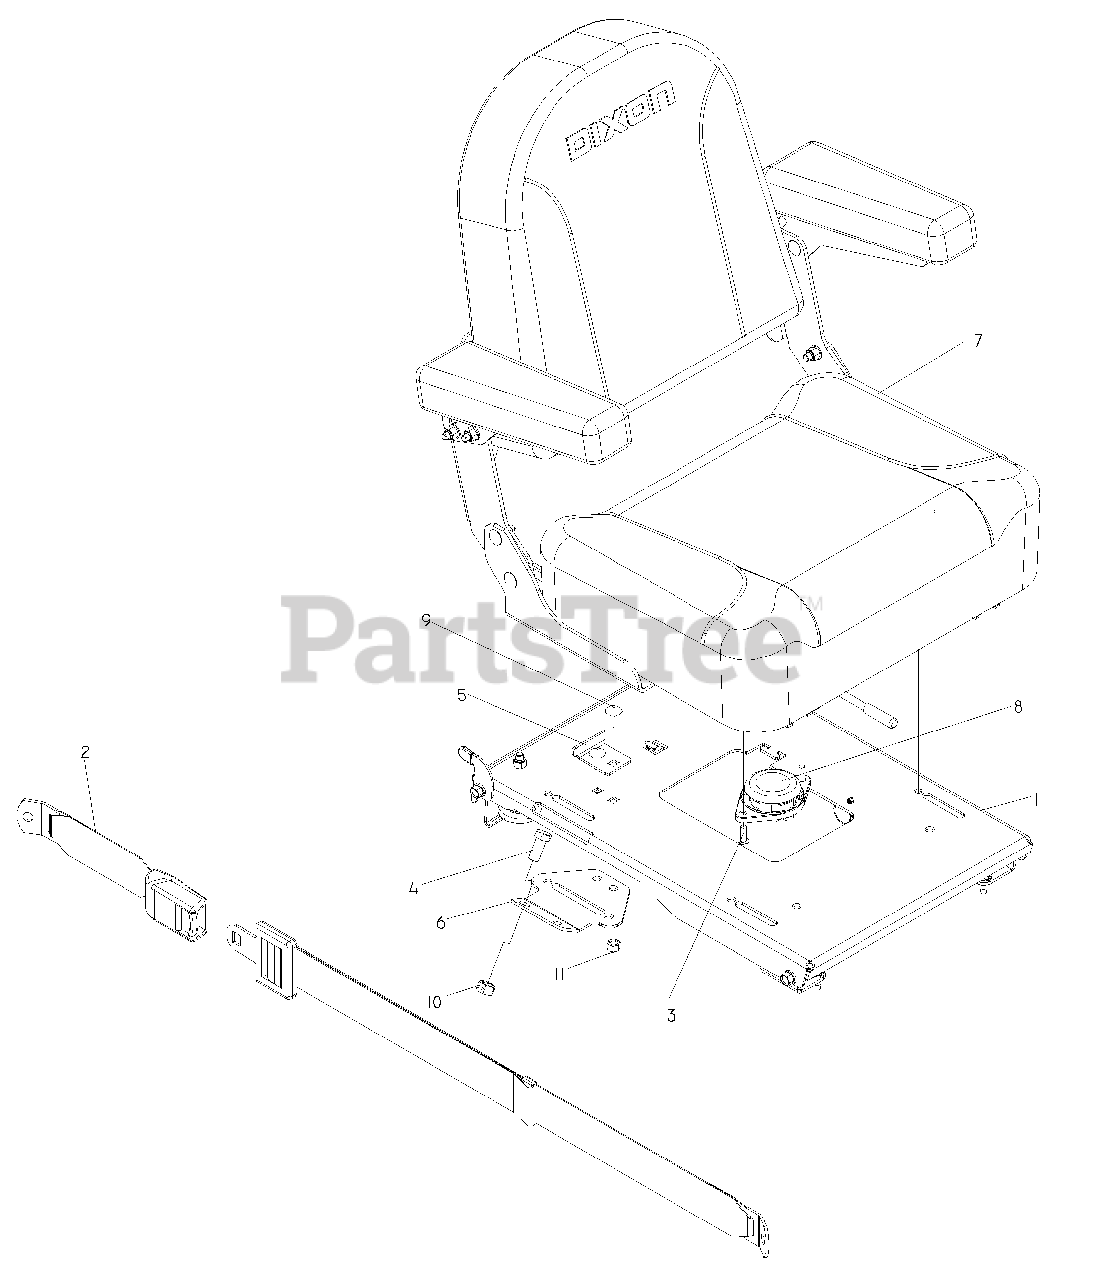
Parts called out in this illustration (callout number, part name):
2	SEAT BELT
3	SCR 1/4-20X3/4 SLTD RDHD GR2ZD
4	HCS 7/16-14 X 1 GR 5 ZD
5	STOP, SEAT - BLACK
6	MOUNT, SEAT BELT
7	SEAT ASM W/SLIDE
8	SEAT SWITCH KIT
9	RHSNB 5/16-18 X 3/4
10	NUT 7/16C CENTERLOCK
11	NUT 5/16 NYLOC
